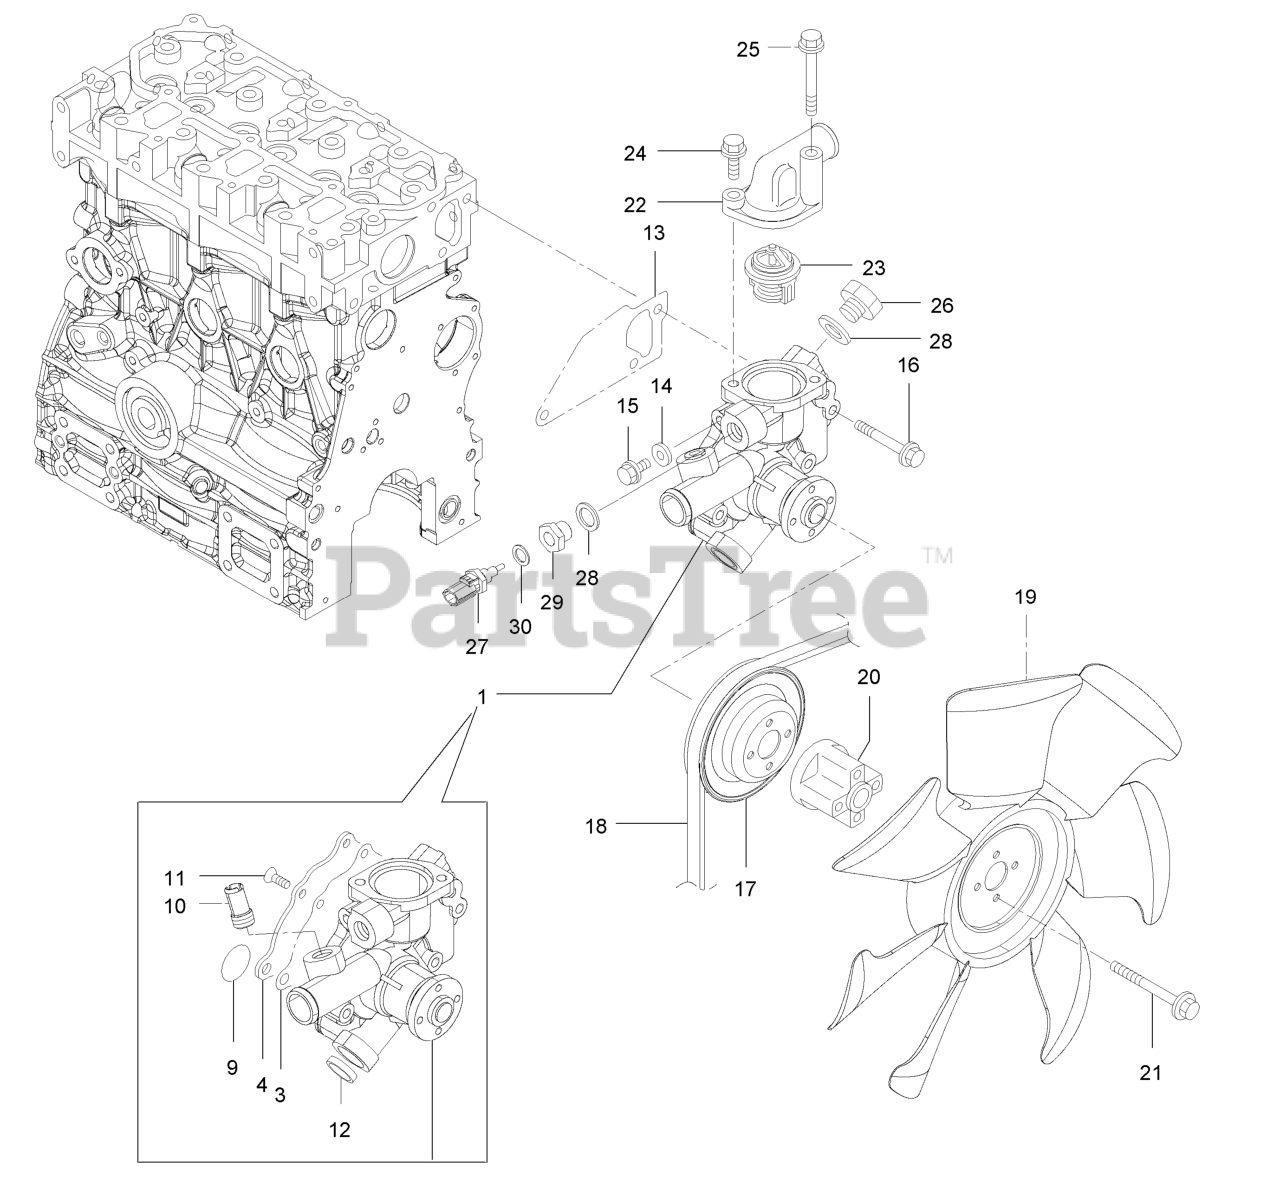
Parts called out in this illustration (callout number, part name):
1	Pump ASM-Water
10	Joint-Pipe
13	Gasket-Water Pump
17	V-Pulley
19	Fan-Cooling 1
20	Spacer-Fan
22	Cover-Thermostat
23	Thermostat
27	Sensor-Thermostat, CW
30	Washer-Seal
